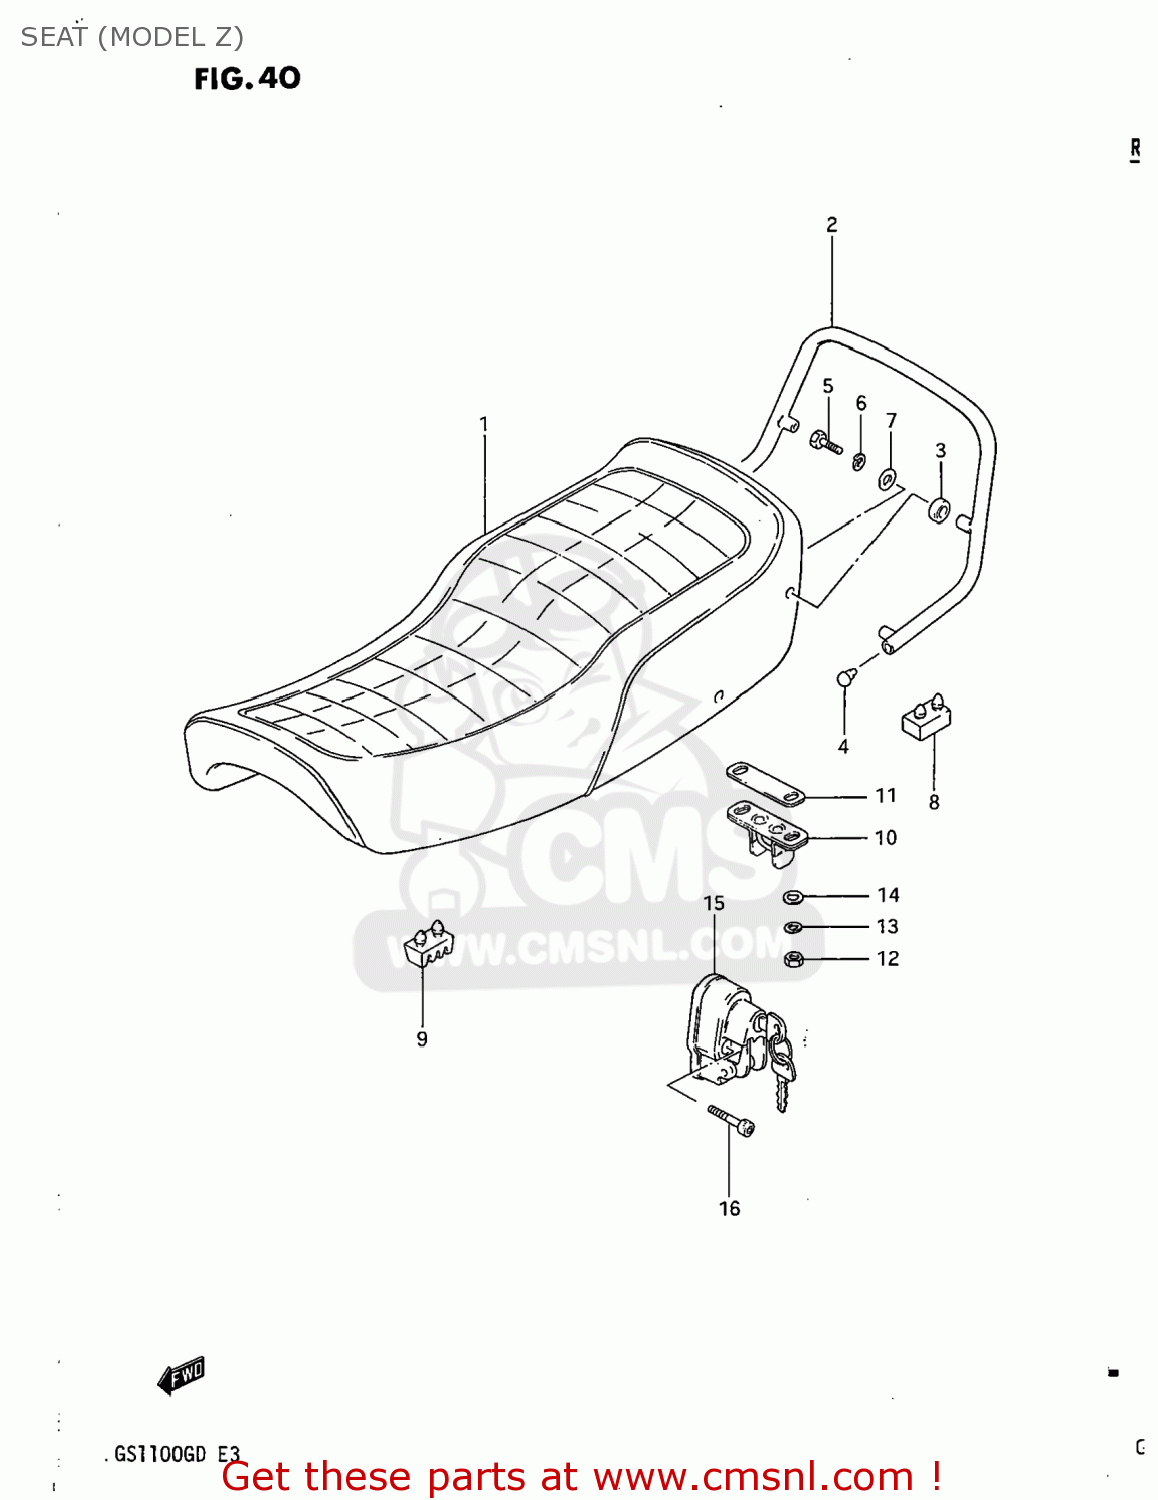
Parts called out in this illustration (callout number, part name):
1	SEAT ASSEMBLY
2	HANDLE,PILLION RIDER
3	CUSHION
4	END,SHEET HANDLE
5	BOLT
6	LOCK WASHER
7	WASHER
8	CUSHION(40X23X12.7)
9	CUSHION,SUPPORT(50X25X32)
10	STRIKER,SEAT LOCK
11	SHIM,SEAT LOCK STRIKER
12	NUT 6MM
13	LOCK WASHER
14	WASHER
15	LOCK ASSY,HELMET
16	BOLT 5X25
